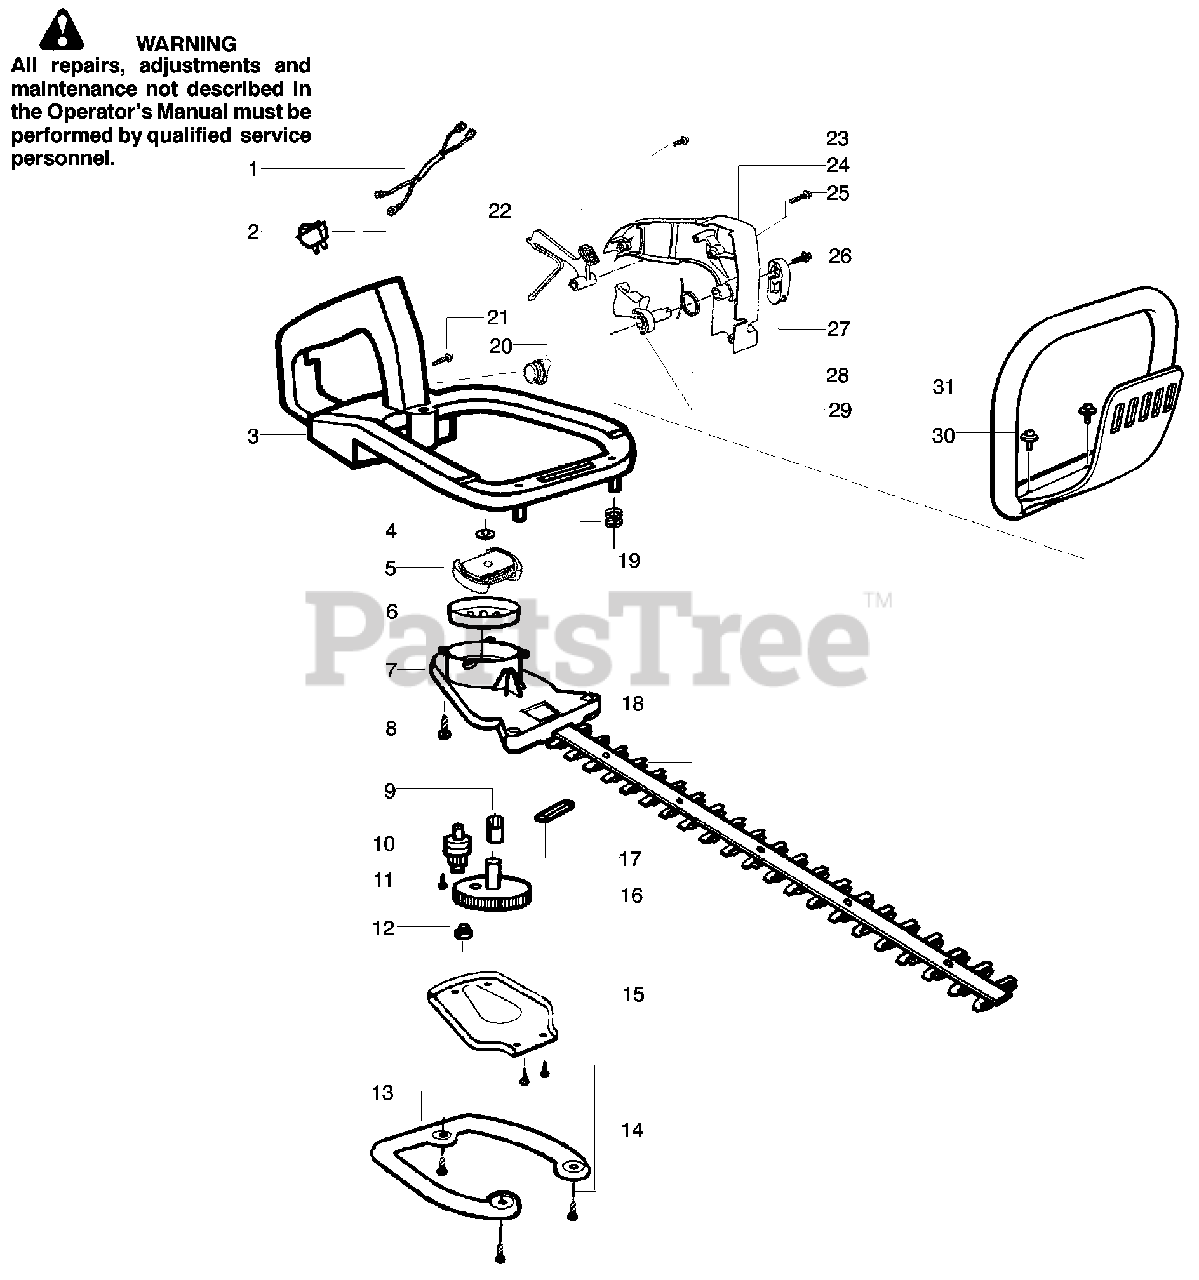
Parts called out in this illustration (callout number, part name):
1	Assy-Leadwire/Switch
2	Switch-Ignition
3	Assy-Rear Handle & Tank
4	Washer-Clutch
5	Kit-Clutch Assy.
6	Assy-Drum
7	Assy-Gear Box
9	Bearing-Gear
10	Assy-Pinion
11	Screw
12	Bushing-Blade
13	Plate-Isolator
15	Cover-Gear Box Plate
16	Kit-Drive Gear Ass'y.
17	Seal-Blade (Felt)
18	Assy-Blade Blade 19"
18	Assy-Blade Blade 22"
20	Assy-Fuel Cap
22	Lockout-Throttle
24	Cover-Handle
27	Lever-Trigger
28	Spring-Trigger
31	Handle-Front
